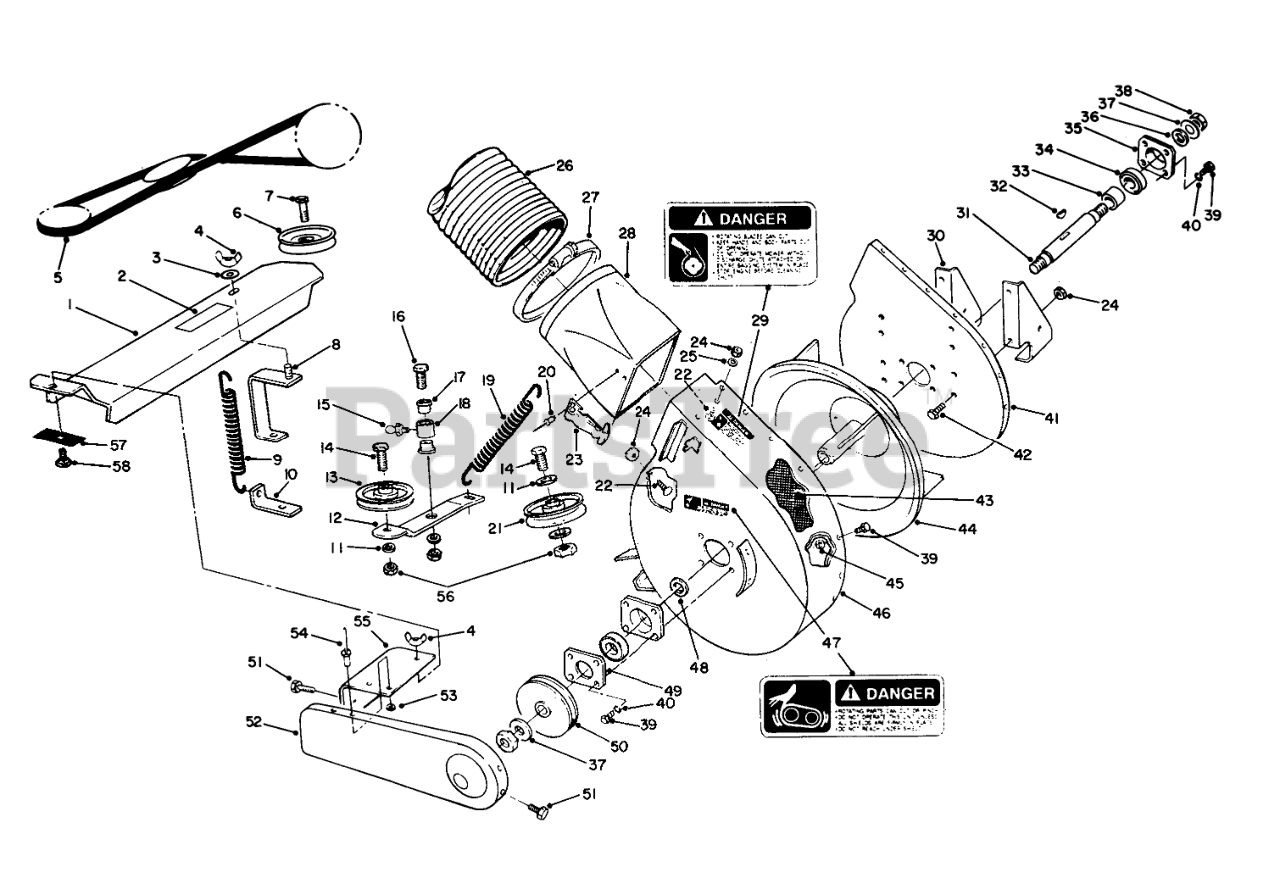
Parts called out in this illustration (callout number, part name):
1	Cover-Belt
2	DECAL-DANGER
3	WASHER-FLAT
4	NUT-WING, LOCK
5	V-BELT
6	PULLEY
7	SCREW-HH
8	OBS BRACKET - WELDED B
9	SPRING-EXTENSION
10	BRACKET B
11	WASHER-FLAT
12	ARM-IDLER-WELDED B
13	Pulley-Idler
14	SCREW-HH
15	FITTING-GREASE
16	SCREW-HH
17	BUSHING
18	SPACER
19	SPRING - EXTENSION
20	RIVET-POP
21	"V" Pulley
22	BOLT-CARR
23	HANDLE ASM
24	Nut_Lock
25	WASHER-PLAIN
26	HOSE 6" X 48"
27	CLAMP
28	ADAPTER
29	DECAL-DANGER
30	BRACKET-BLOWER MT B
31	SHAFT- BLOWER
33	SPACER
34	BEARING-BALL
35	CUP-BEARING
36	Washer
37	WASHER-SPECIAL
38	NUT 5/8-11 L.H.
39	SCREW-HH
40	WASHER-LOCK
41	Plate-Mount
42	SCREW-HH
43	STRIP-WEAR
44	IMPELLER - WELDED BLACK
45	NUT-LOCK, NI
46	Blower
47	DECAL-DANGER
48	SPACER-BEARING
49	Cover-Plate
50	PULLEY-BLOWER R
51	Bolt
52	SHIELD
53	Washer
54	RIVET-BLIND
55	SHIELD-PULLEY B
56	NUT-LOCK, NI
57	STRAP B
58	SCREW-CARR
